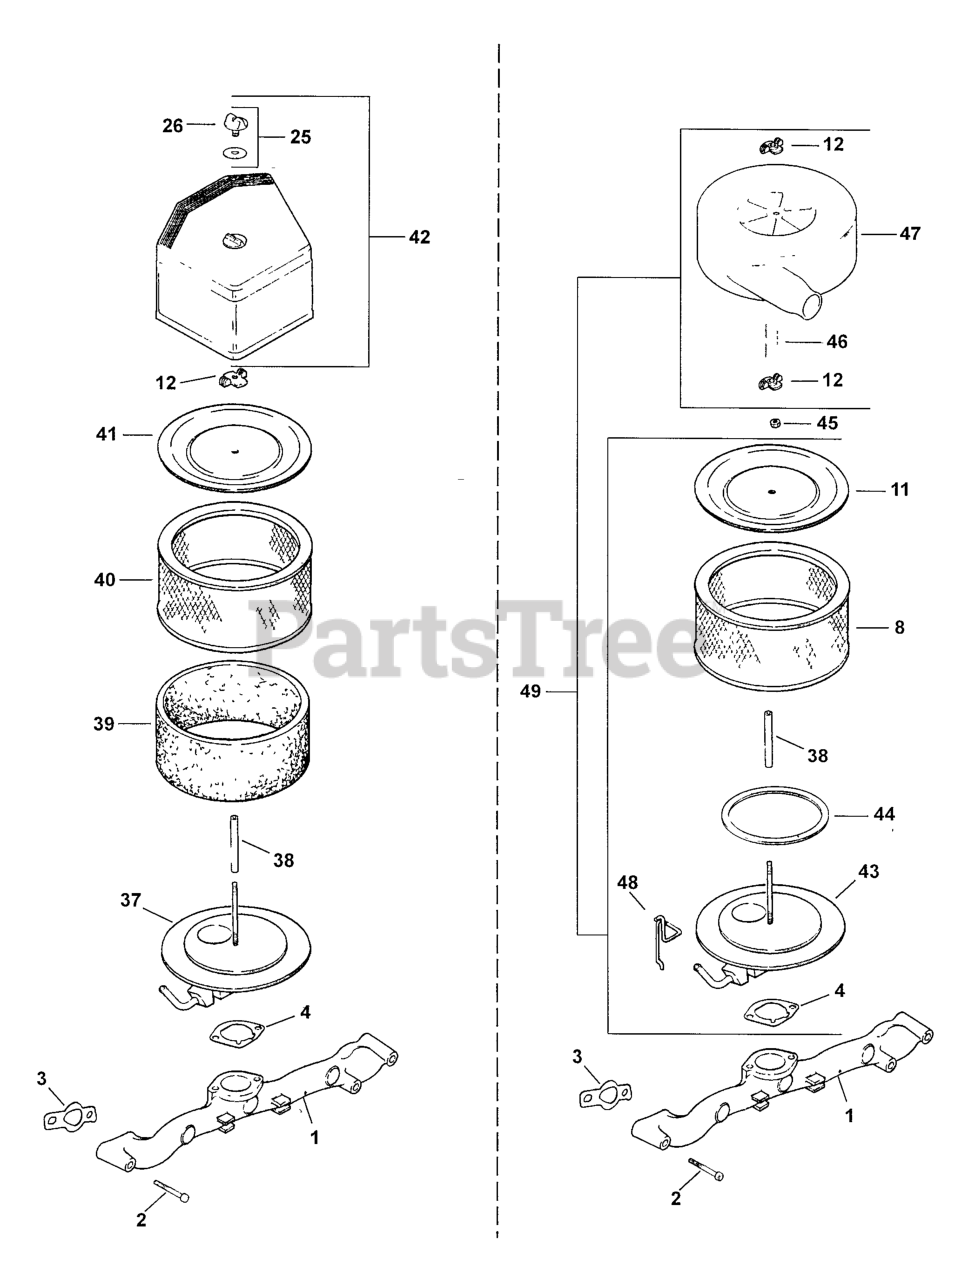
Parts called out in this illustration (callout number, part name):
1	Manifold, Intake
2	Screw, Hex. Flange M6x1.0x55
3	Gasket, Intake Manifold
4	Gasket, Air Cleaner Base
12	Nut, Wing
25	Kit, Air Cleaner Knob W/ Gasket
26	Knob, Air Cleaner Cover
37	Elbow, Air Cleaner
39	Element, Precleaner
40	Element, Air Cleaner
41	Cover, Air Cleaner Element
42	Kit, Air Cleaner Cover
